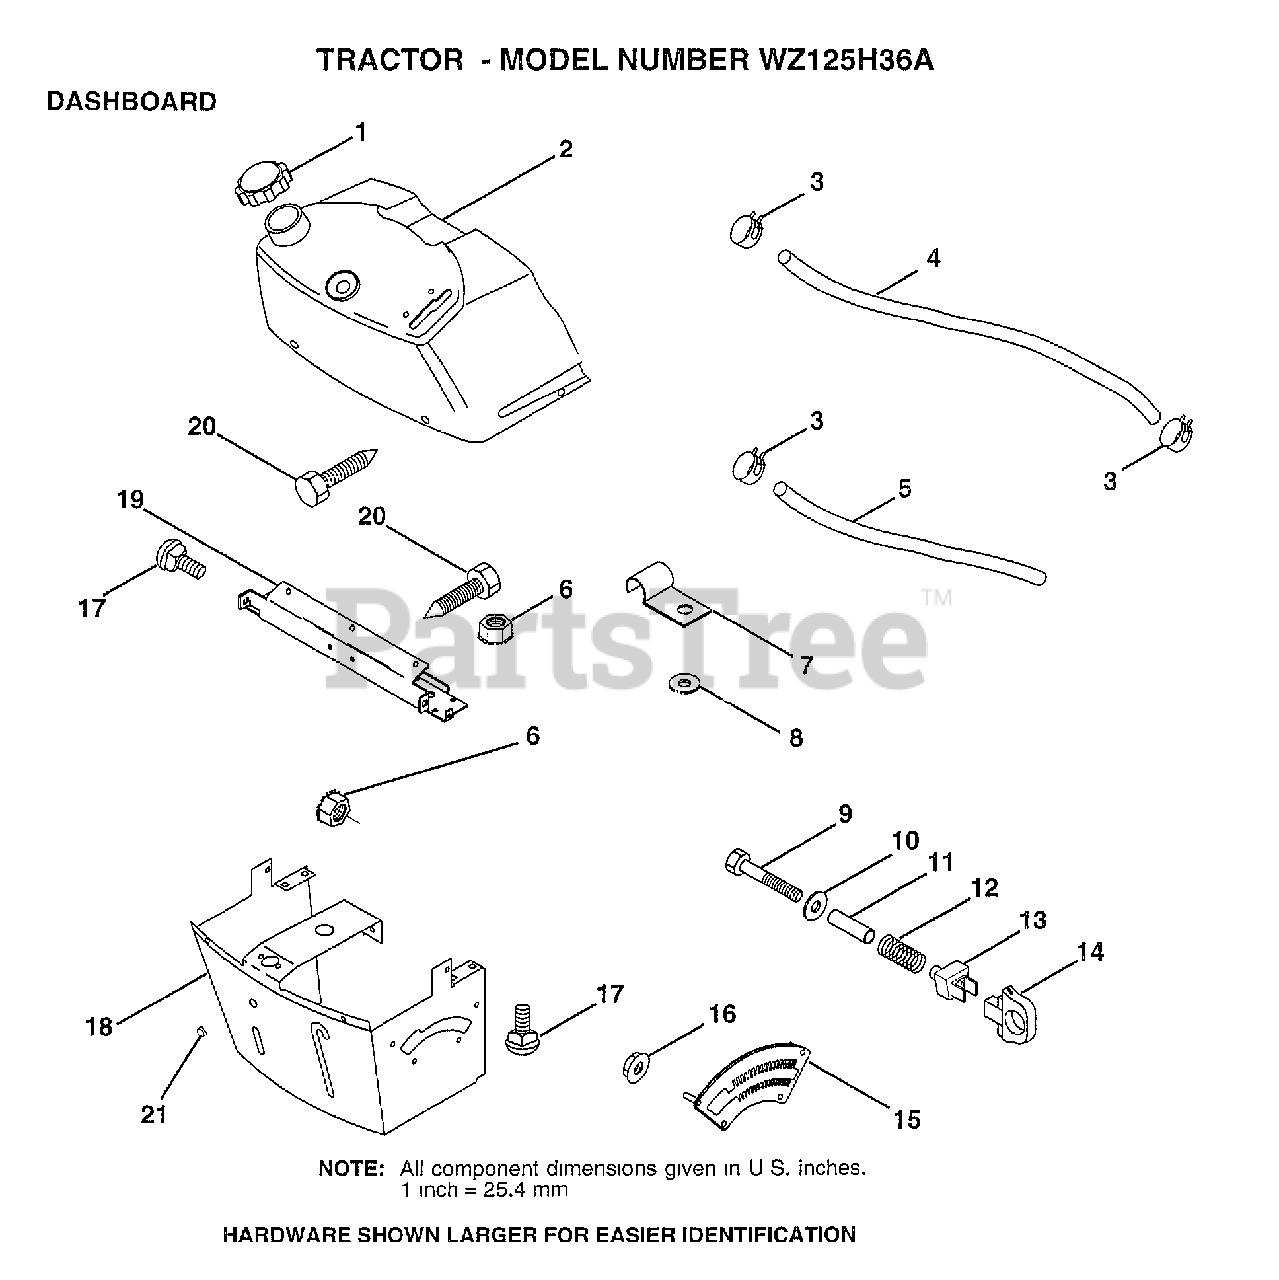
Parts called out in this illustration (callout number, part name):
1	CAP BLK FUEL LR
2	TANK.ASM.DASH.LR
3	HOSE CLAMP
5	FUEL LINE T
6	NUT HXKEP 1/4X20
7	CLIP T
8	WASHER PM
9	BOLT
11	SPACER SPLIT
12	SPRING M
13	"KNOB,HGT RETAINER"
14	KNOB
15	ADJUSTER QUAD
17	BOLT
18	SUPT ASSY DASH
19	CROSS BRACE
20	SCREW.1/4-20X1/2
21	PLUG DOME
